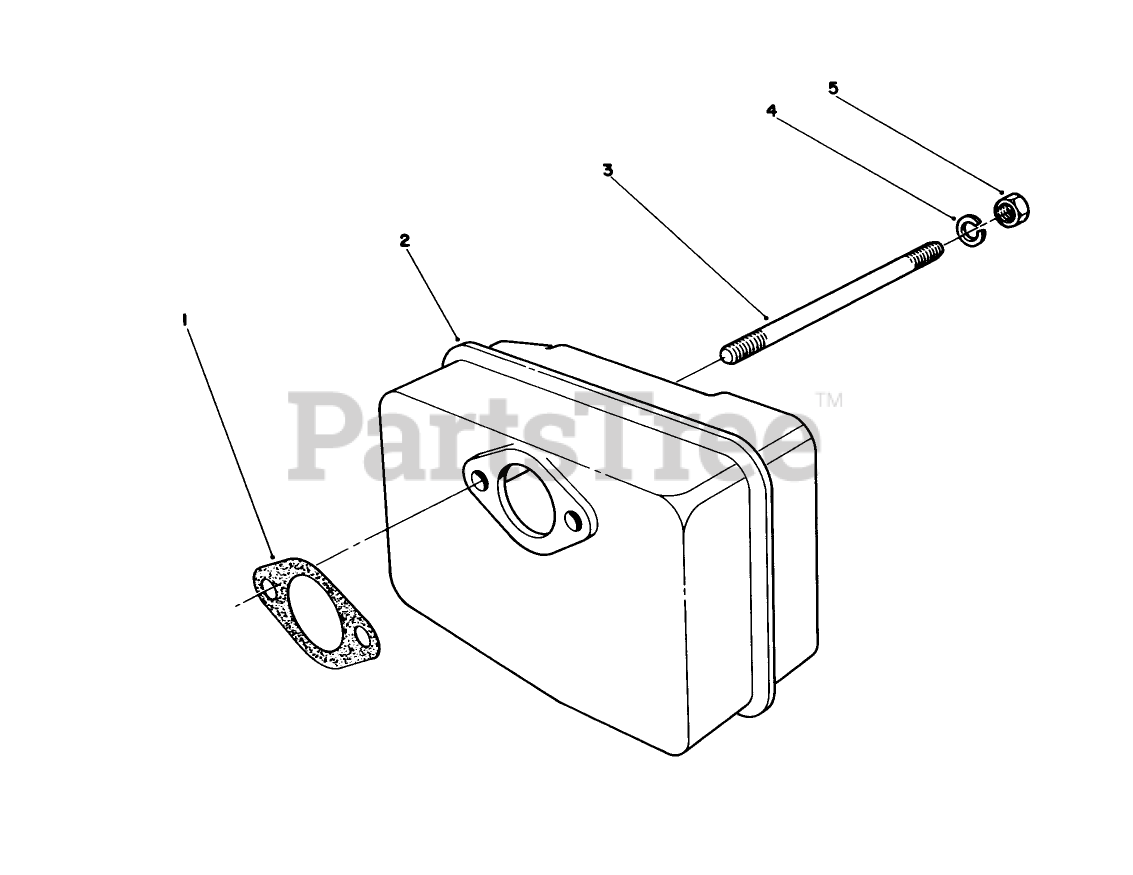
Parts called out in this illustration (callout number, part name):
1	GASKET
2	MUFFLER
4	WASHER-LOCK
